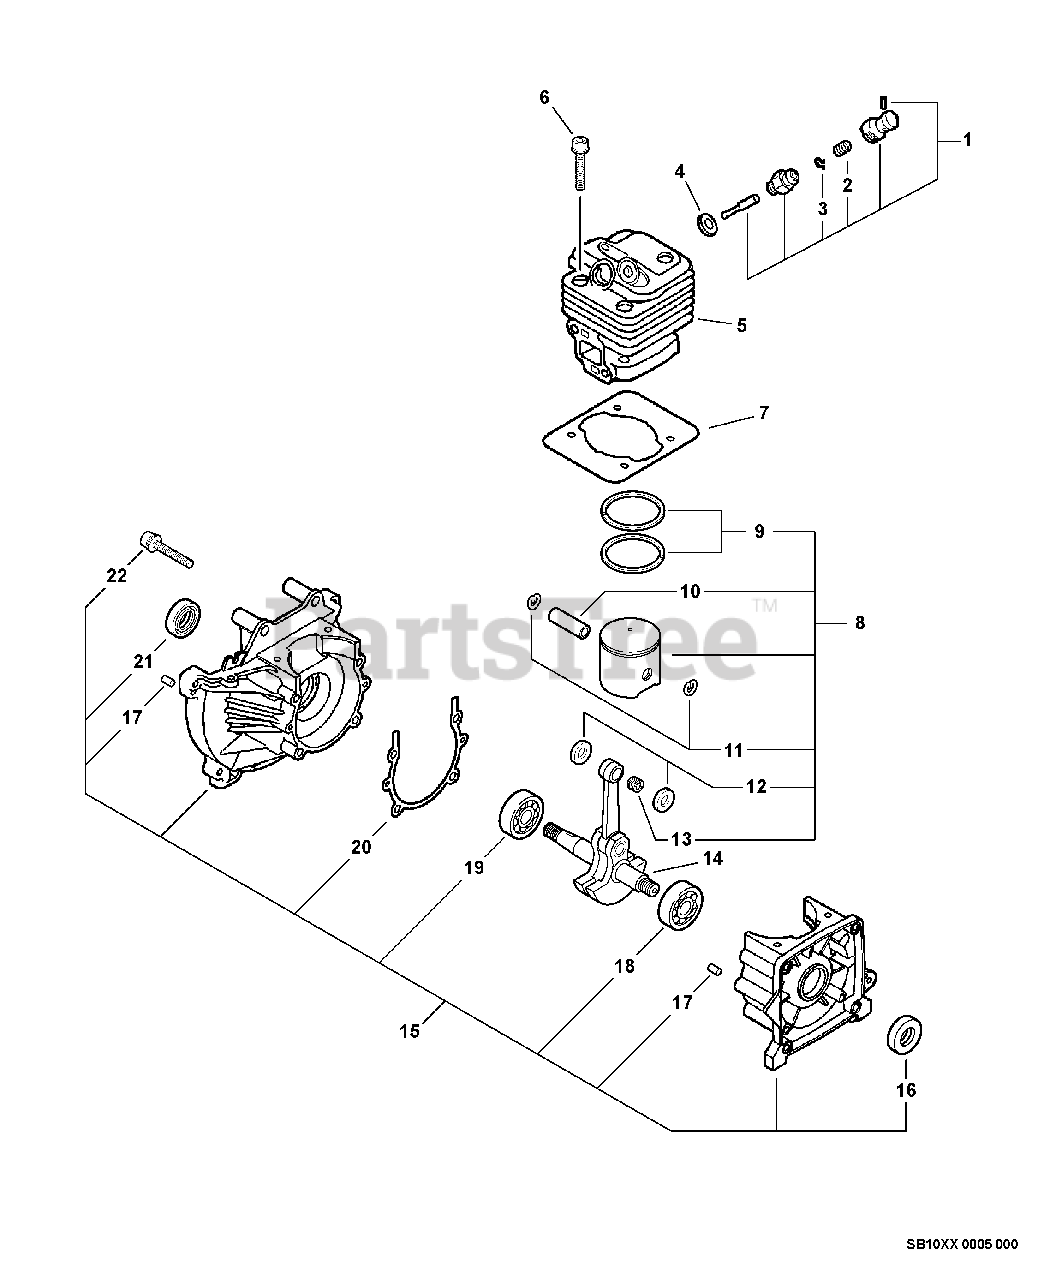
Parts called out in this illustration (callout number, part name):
1	DECOMPRESSION ASSY
4	WASHER
5	CYLINDER
6	SCREW - 5X20
7	GASKET, CYLINDER
8	PISTON KIT
9	RING, PISTON
10	PIN, PISTON
11	RING, RETAINING - 8
12	WASHER - 10
13	BEARING, NEEDLE
14	CRANKSHAFT ASSY
15	CRANKCASE KIT
16	SEAL, OIL
17	PIN - LOCATING
18	BEARING, BALL - 6202
19	BEARING, BALL - 6201
20	GASKET, CRANKCASE
21	SEAL, OIL
22	SCREW - 5X35
